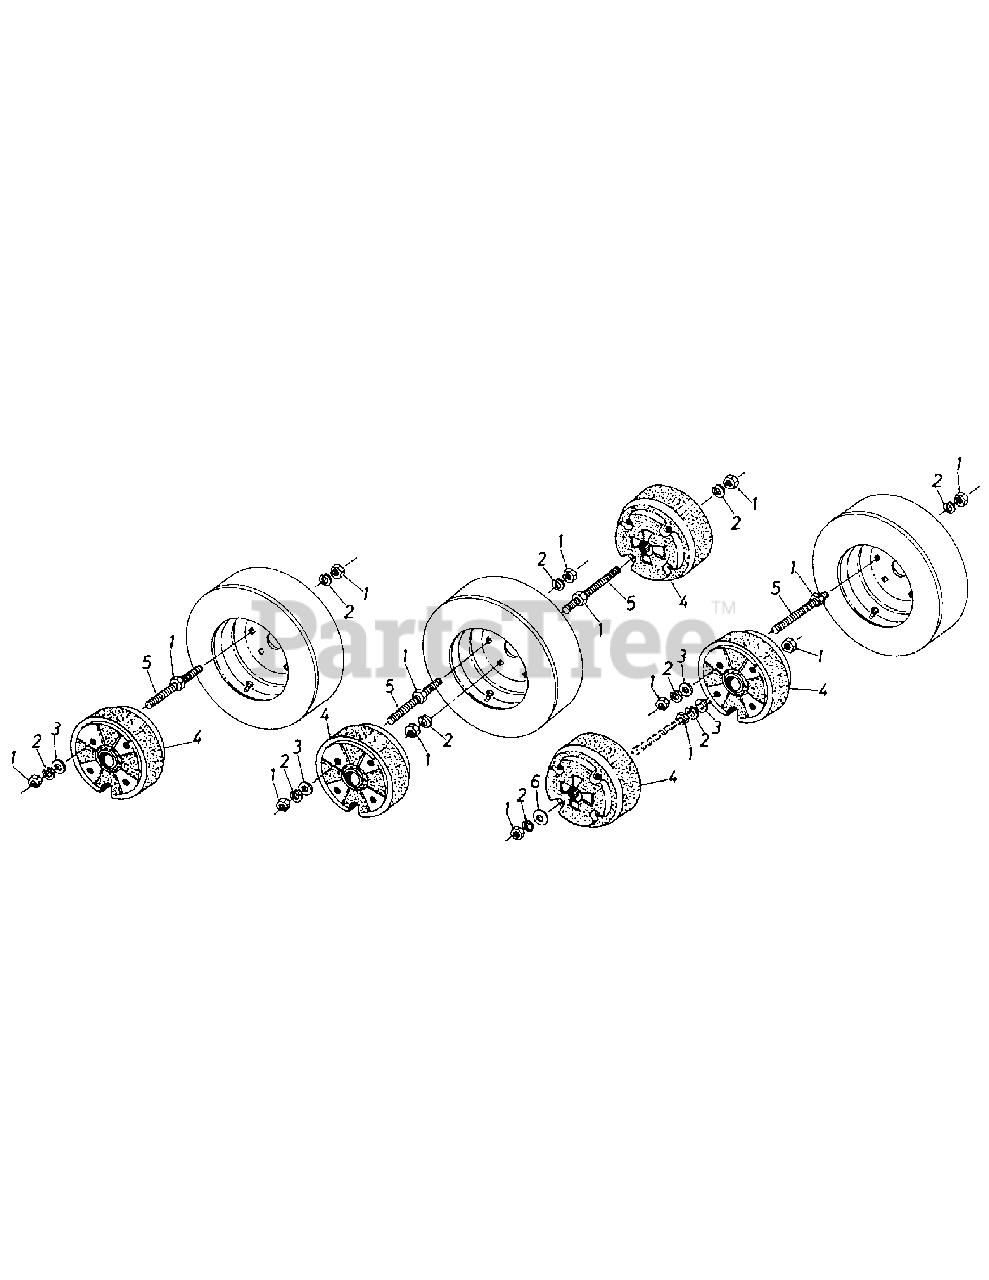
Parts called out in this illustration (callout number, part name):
1	Nut,Hex 1/2-13 Thd.
2	Washer,Lock 1/2 ID
3	Washer, Flat .53 x 93
4	Wheel Weights, 50lb
4	WEIGHT, KIT
5	Rod, Threaded 1/2-13 x 9.5
6	Washer, Flat .5 x 2.0
